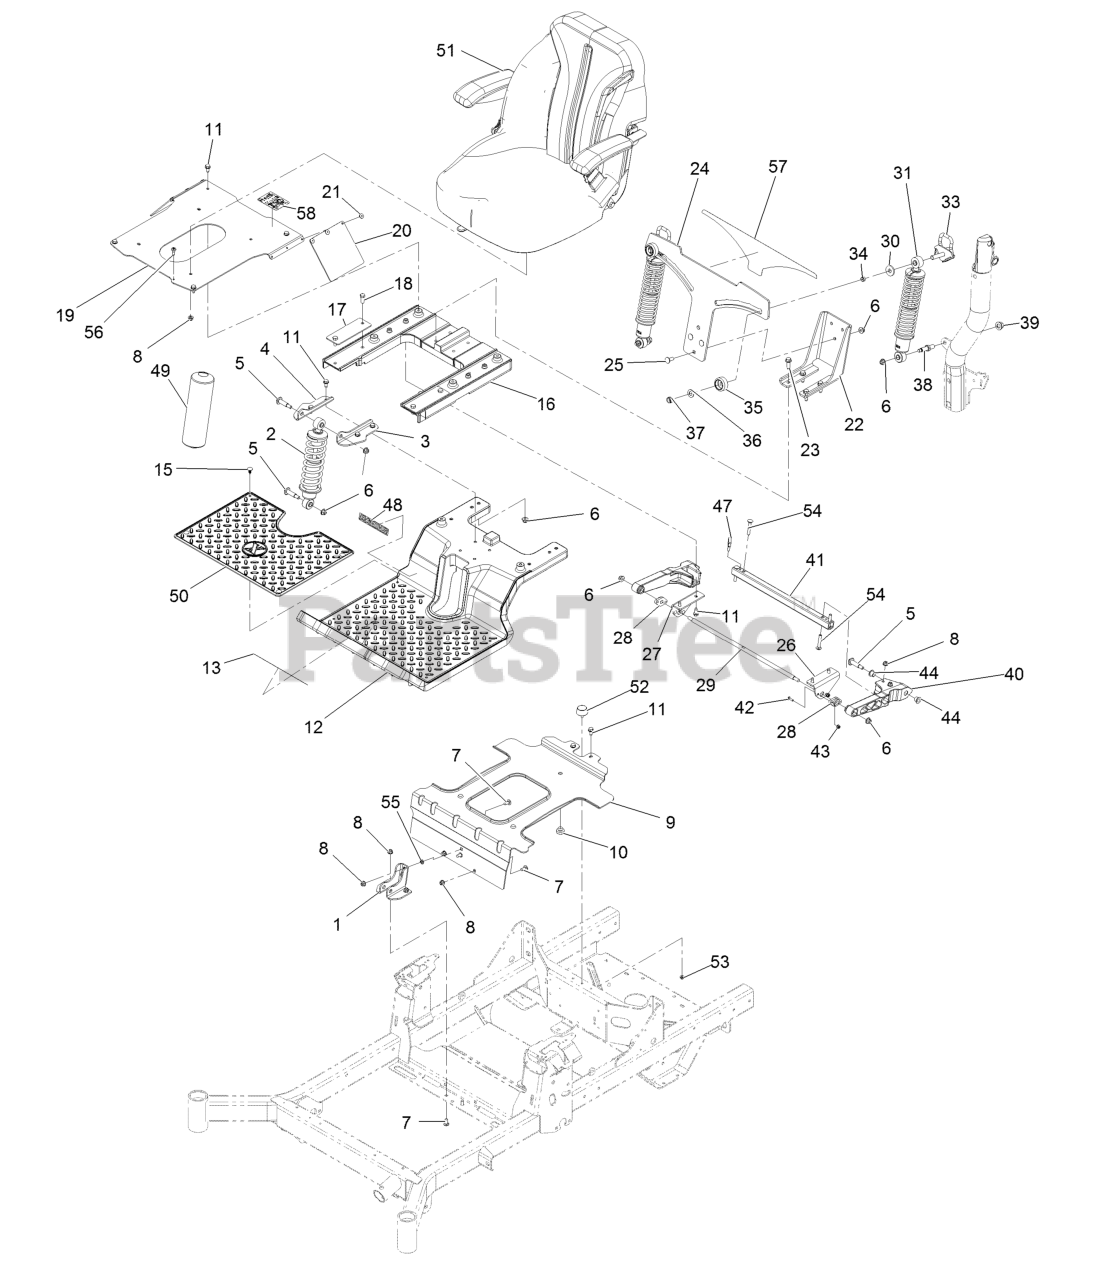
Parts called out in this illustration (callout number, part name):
1	Bracket-Shock, Front Lower
2	Shock/Spring
3	Bracket-Shock Mount, Upper (LH)
4	Bracket-Shock Mount, Upper (RH)
5	Bolt-Shoulder, HWH
6	Nut-Nyloc 3/8-16 Flg
7	Bolt-Carriage 5/16-18 X 3/4 Short Neck
8	Nut-Nyloc 5/16-18 Flg
9	Bracket-Tank
10	Bumper-Seat
11	Screw-HWH 5/16-18 X 3/4 Tf
12	Subframe-Front
13	Decal-Danger
15	Plug-Plastic
16	Subframe-Rear
17	Plate-Backer
18	Screw-HH 3/8-16 X 1
19	Plate-Seat
20	Flap-Rubber
21	Rivet-Pop
22	Bracket-Mount, Lower
23	Screw-HWH 3/8-16 X 1 1/4 Taptite
24	Plate-Mounting, Adj Shock
25	Bolt-Carriage 3/8-16 X 1
26	Bracket-Arm, Trailing (LH)
27	Bracket-Arm, Trailing (RH)
28	Bearing-Flange
29	Rod-Pivot
30	Washer-Plastic
31	Shock/Spring ASM
33	Cam Lock ASM
34	Bearing-Sleeve
35	Knob-Lock, Cam
36	Washer-Adjusting
37	Nut-Nyloc 1/2-13 Thin
38	Bolt-Shoulder
39	Nut-Lock 1/2-13
40	Trailing Arm
41	Tube-Arm, Trailing
42	Screw-CARR
44	Bushing-Flange
47	Clamp-Hose
48	Decal-Radius Logo
49	Cover-Shock
50	Floor Mat
51	ASM-Seat Exmark
53	Nut-Nyloc 1/4-20 Flg
54	Bolt-Carriage 3/16-18 X 2
55	Nut-Push
56	Screw-Shoulder
57	Decal-Adjustment, Ride
58	Decal-Aid, Service
